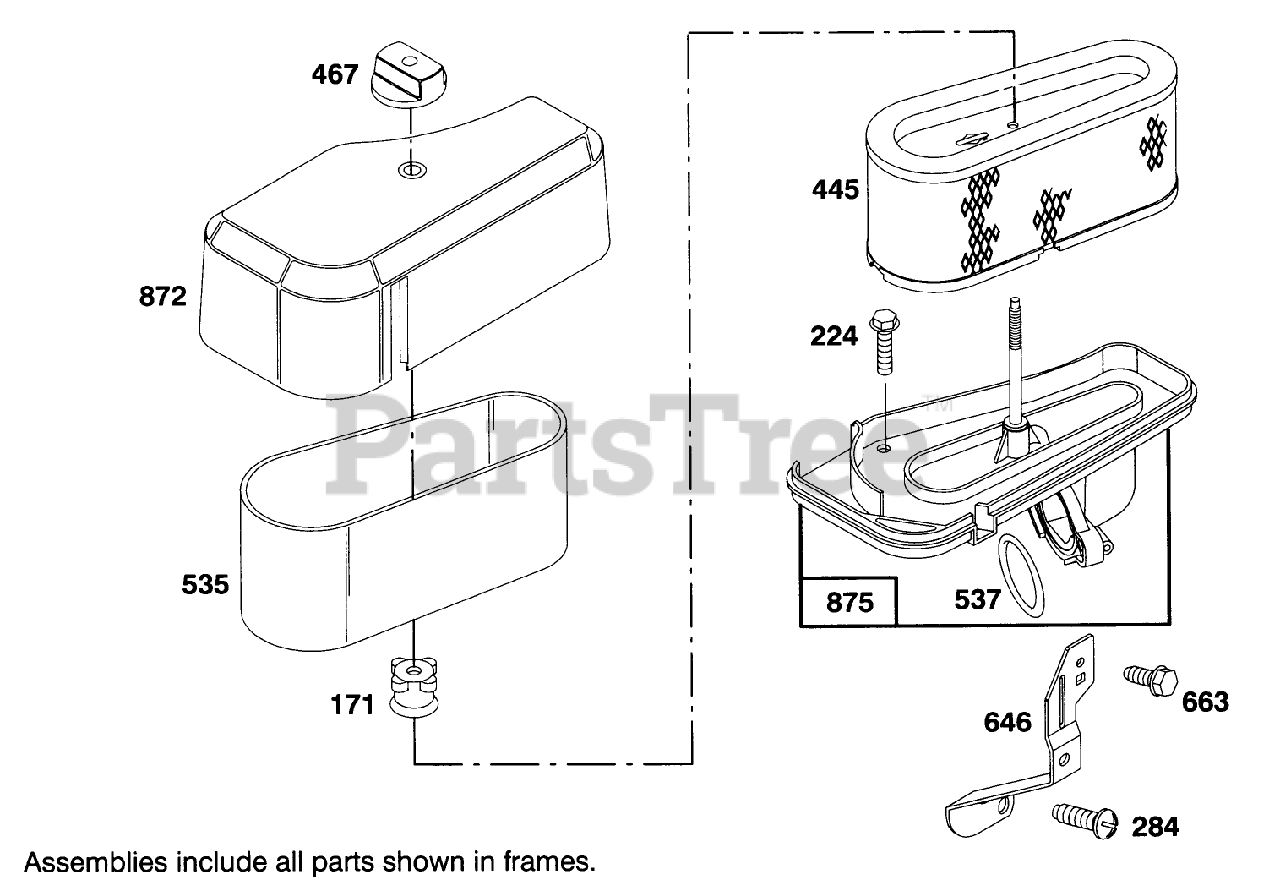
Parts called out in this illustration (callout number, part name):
224	Screw-Sem
284	Screw-Pan Head
445	Filter-Air
535	Filter-Air
537	O-Ring
646	Brace-Air Cleaner
663	Screw
872	Cover-Air Cleaner
875	Base-Air Cleaner
